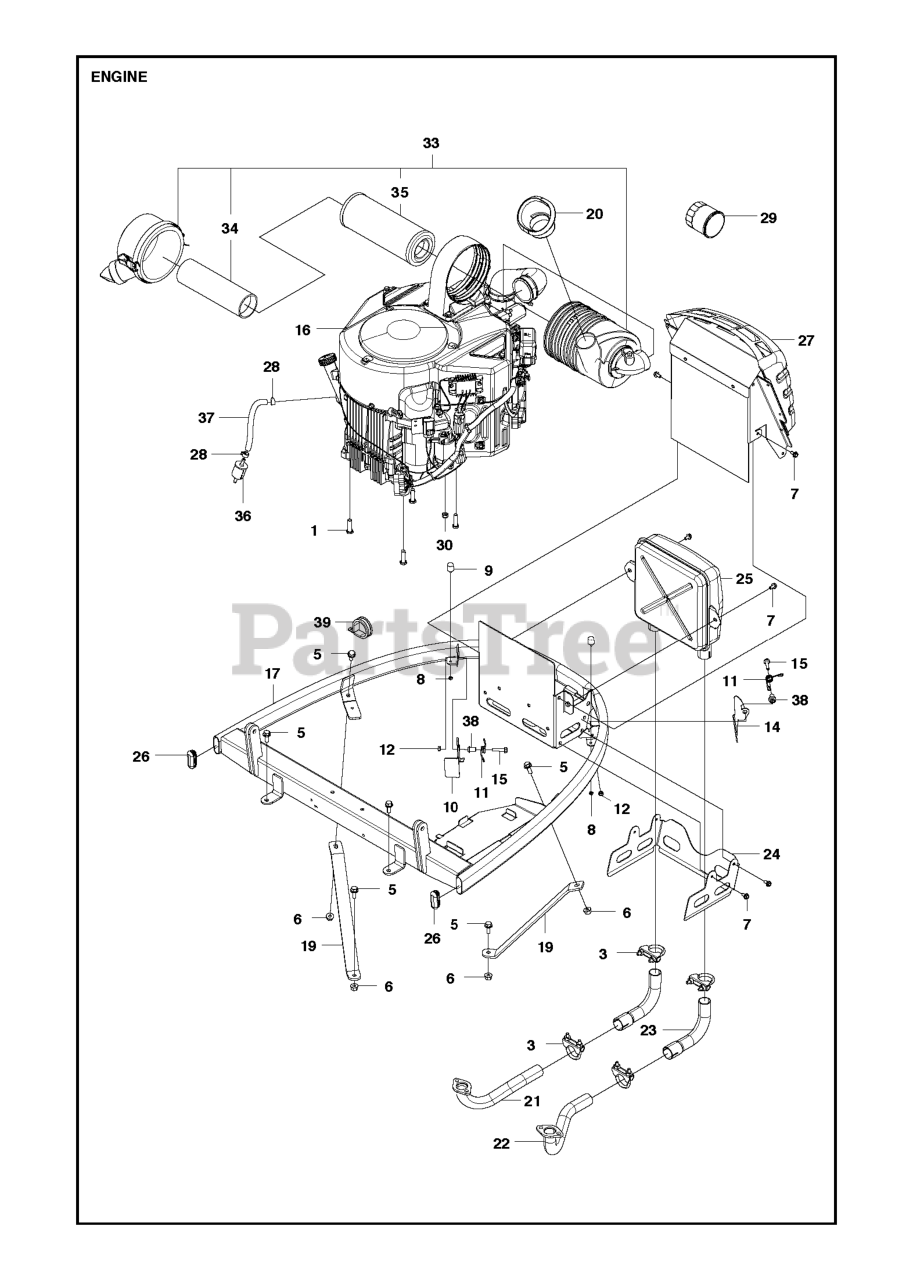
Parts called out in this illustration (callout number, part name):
3	CLAMP ASSY EXHAUST
5	SCREW EHHFM
6	NUT FLANGE
7	BOLT
8	LOCKNUT M5
12	LOCKNUT M6
29	OIL FILTERS
30	NUT
